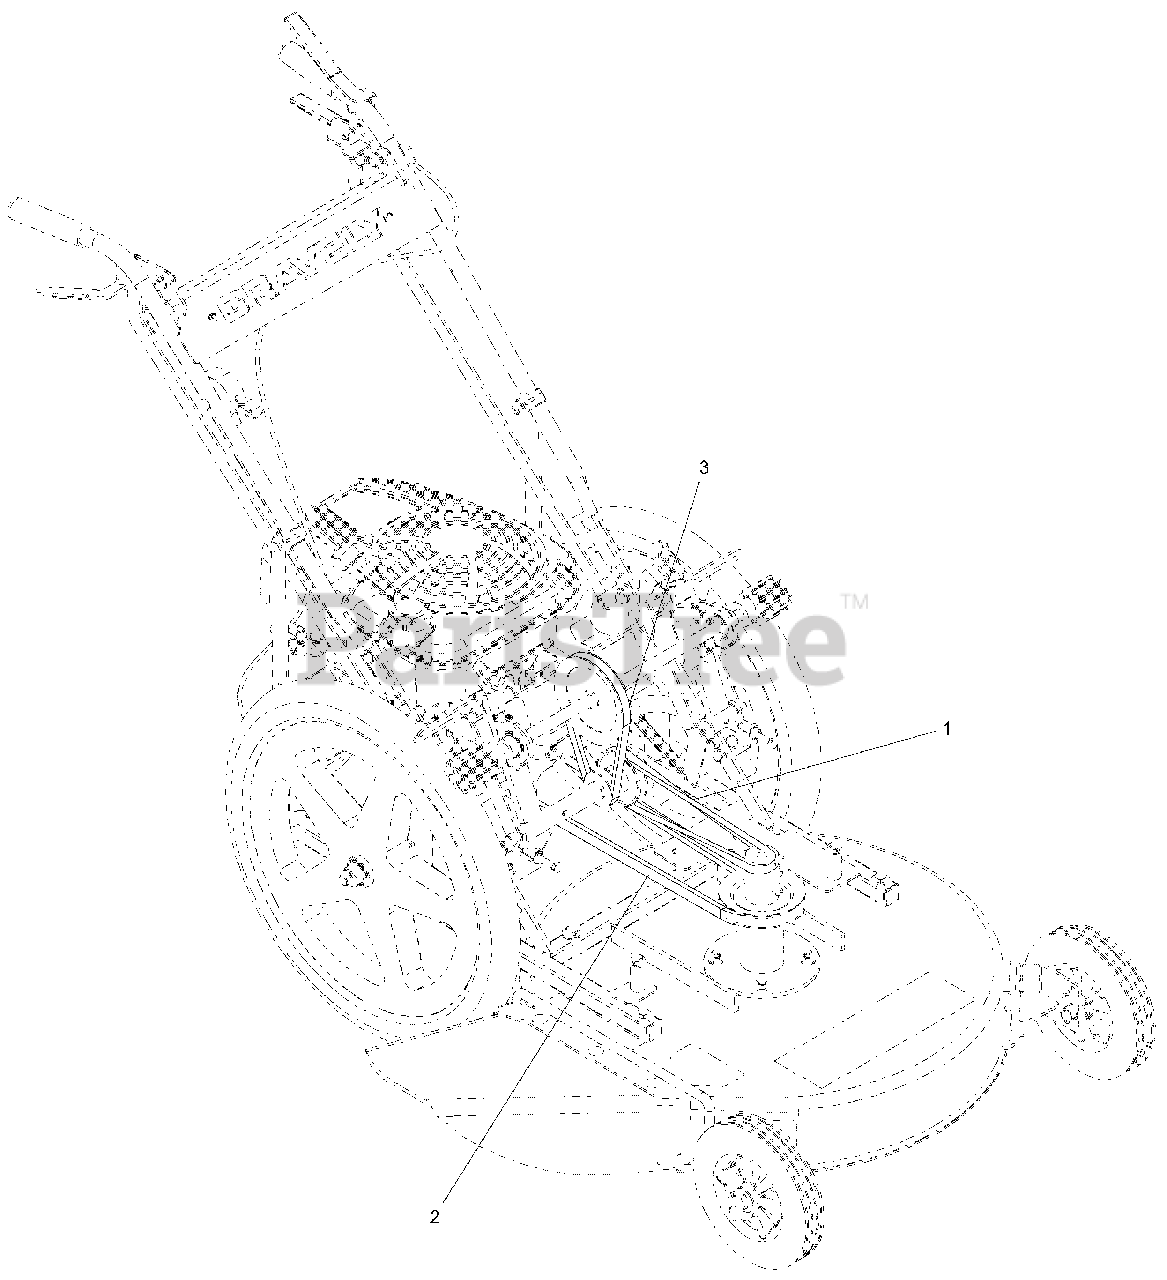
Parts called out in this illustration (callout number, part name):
1	V -BELT, 4L-RAW EDGE
2	V -BELT, HB-WRAPPED
3	V -BELT, 4L-RAW EDGE
